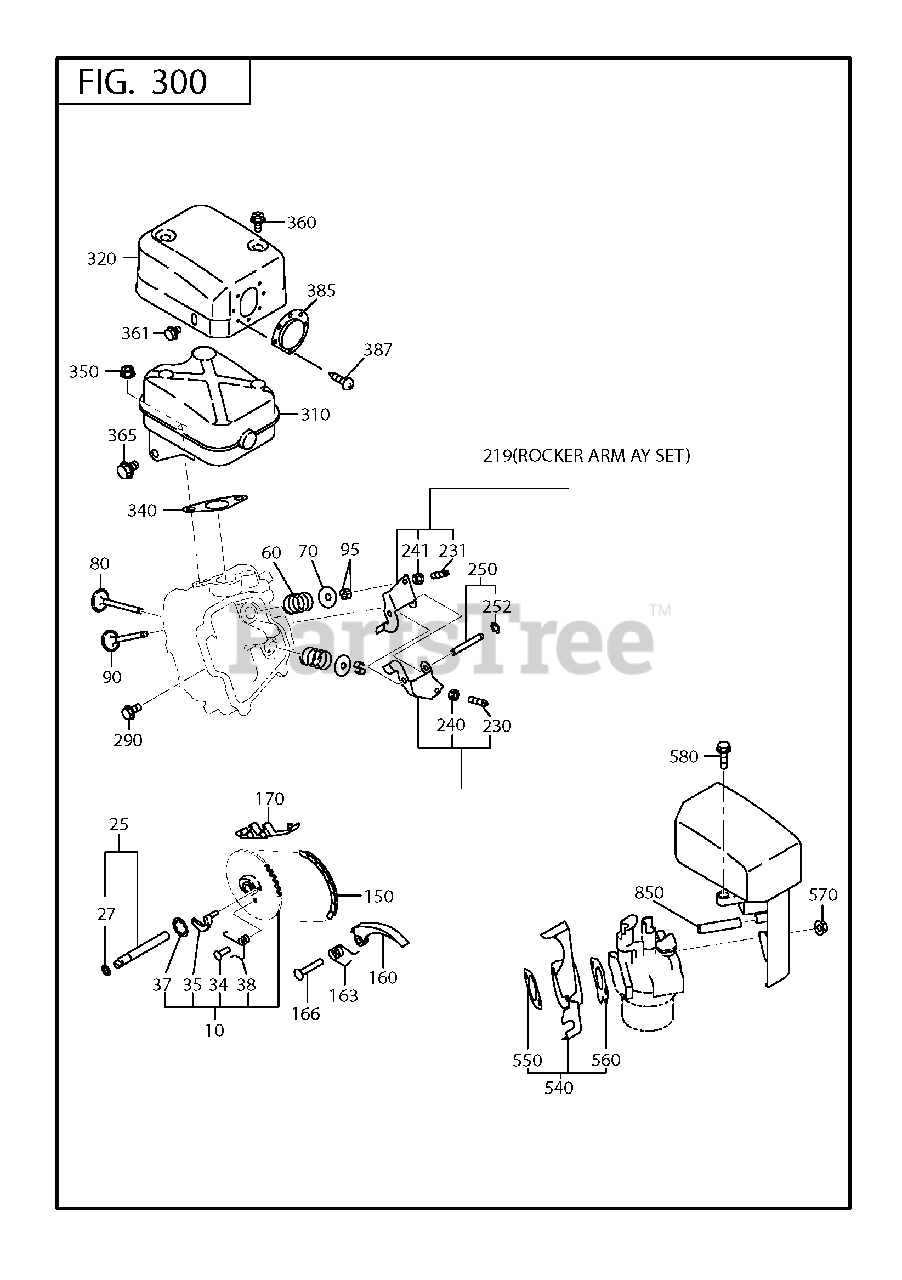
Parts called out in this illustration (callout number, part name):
25	PIN CP,CAMSHAFT
70	SPRING RETAINER
150	TIMING CHAIN CP
163	SPRING, TENTIONER
166	PIN, TENTIONER
219	ROCKER ARM AY SET
250	PIN CP, ROCKER
320	MUFFLER COVER CP
340	GASKET, MUFFLER
550	GASKET 2, INSULATOR
560	GASKET 1, INSUALTOR
